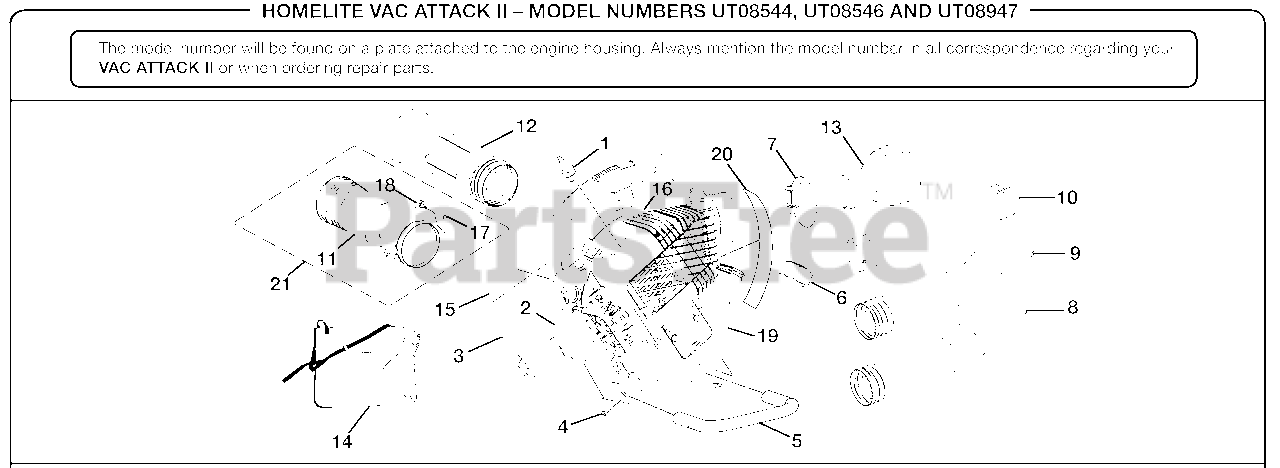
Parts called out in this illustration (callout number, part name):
1	Spark Plug
2	Air Filter
3	Air Box Cover Assembly
4	Screw (8-18 x 1/2 in. Pan Hd.)
5	Lower Handle
6	Fuel Cap Assembly
7	Clamp Assembly
8	High Velocity Nozzle
9	Sweep Nozzle
10	Upper Blower Tube
11	Upper Vacuum Tube
12	Lower Vacuum Tube
13	Vacuum Adaptor
15	Door Decal
16	Starting Label
18	Blower Knob
19	Fuel Tank & Cap Assembly
20	Warning Label
21	Vac Tube, Knob & E-ring Assembly
